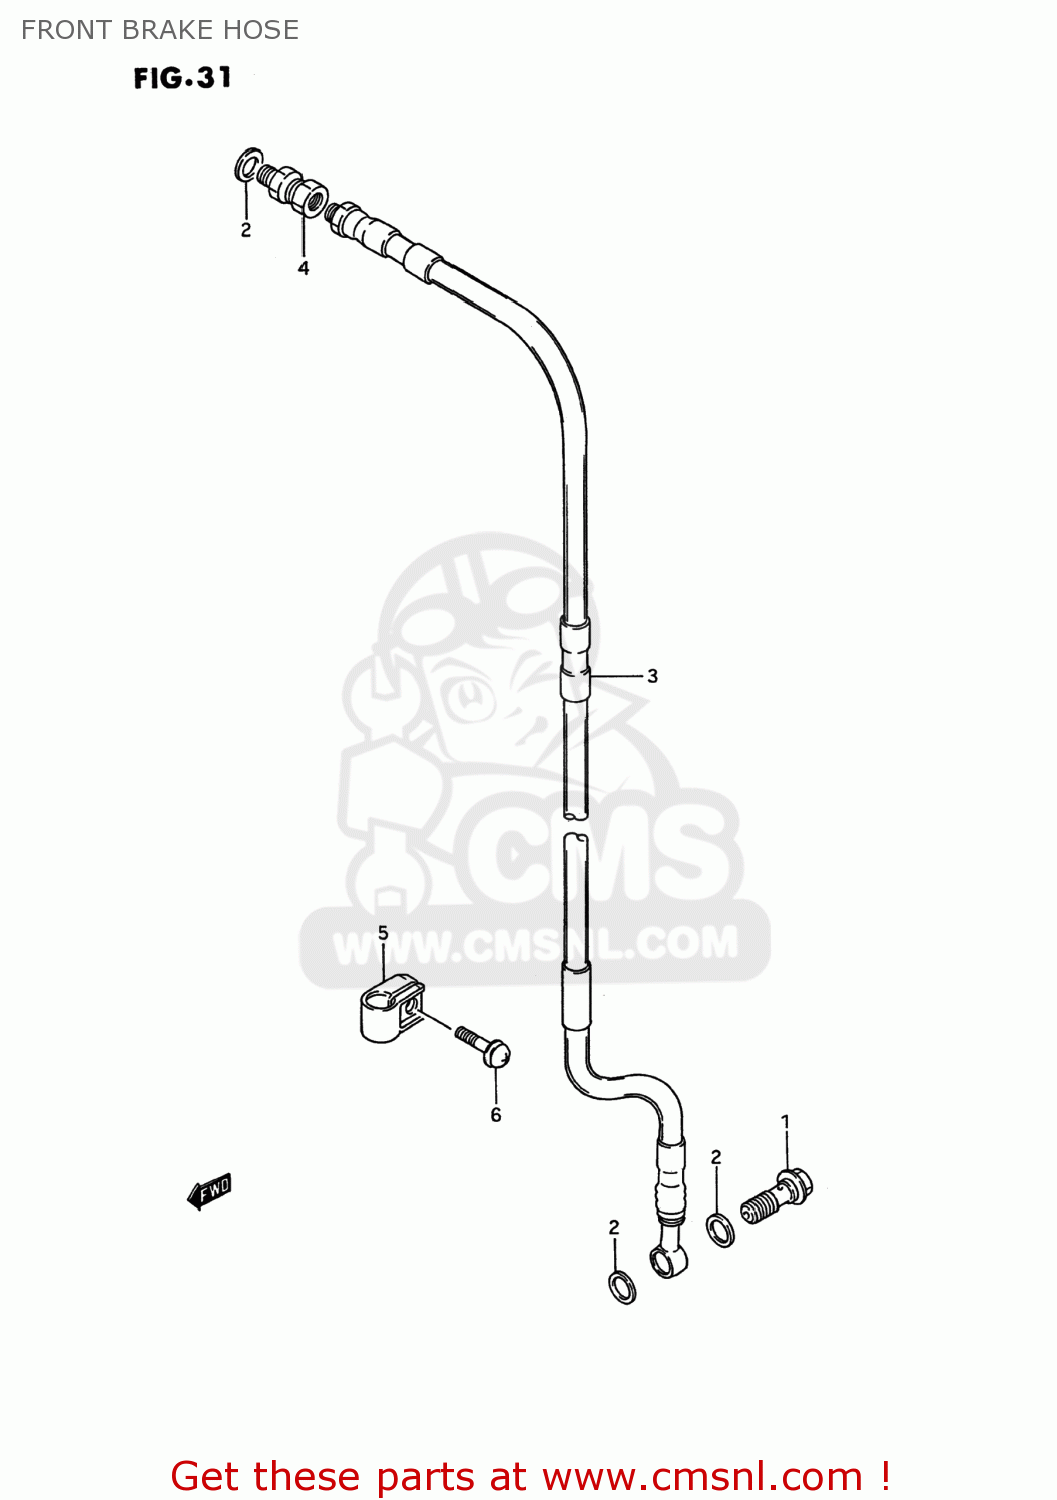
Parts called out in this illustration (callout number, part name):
1	BOLT UNION
2	WASHER(10X15X1.5)
3	HOSE,FR BRAKE
4	ADAPTOR,BRAKE HOSE
5	CLAMP,FRONT BRAKE HOSE
6	SCREW
